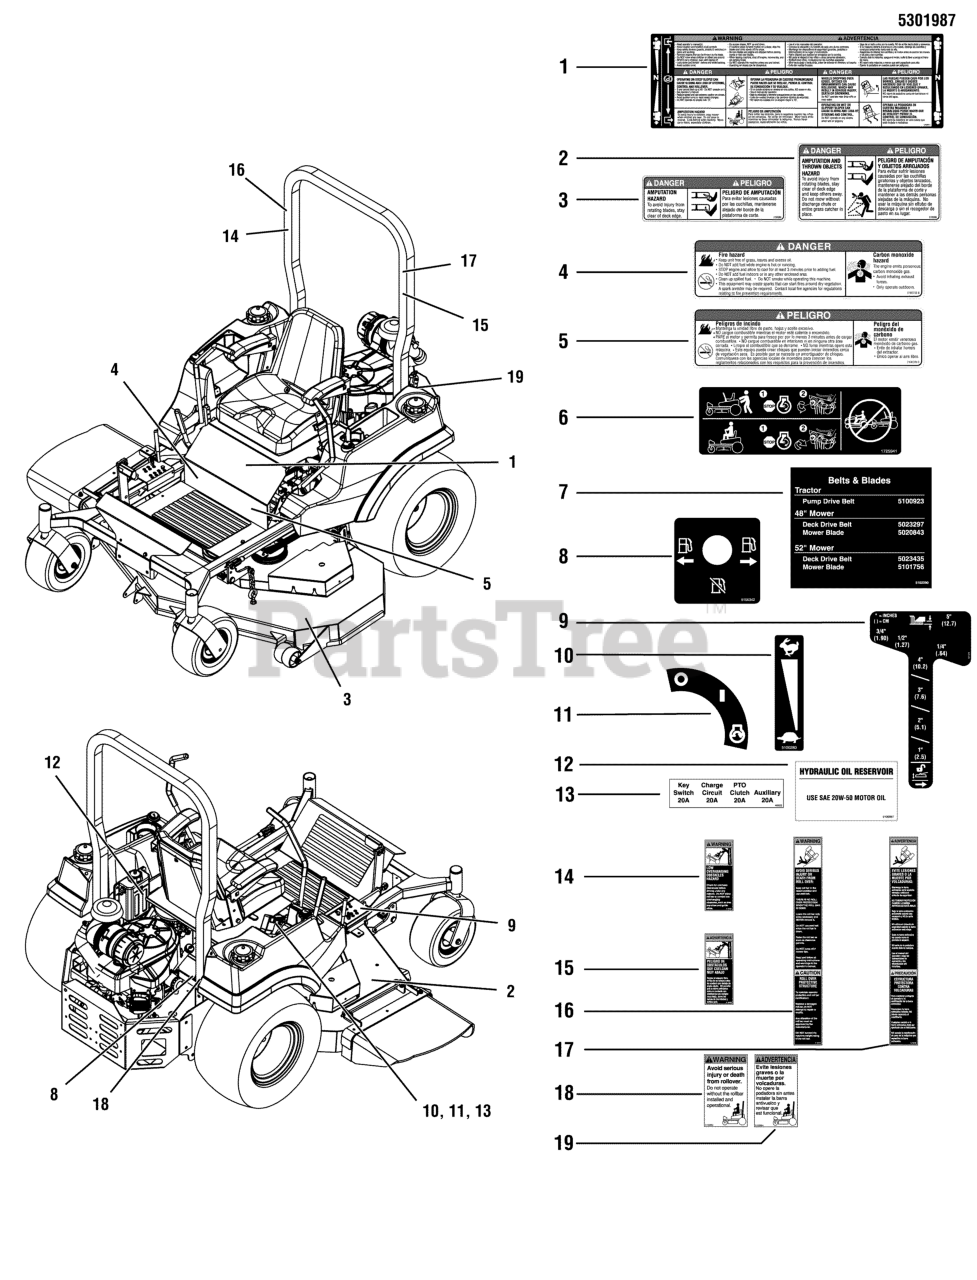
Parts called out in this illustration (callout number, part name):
1	DECAL, MAIN SAFETY
2	DECAL, DANGER, MOWER DISCHARGE
3	DECAL, DANGER, MOWER
4	DECAL, DANGER, FIRE
5	DECAL, DANGER, FIRE (SP)
6	DECAL, CZT HYDRO RELEASE
7	DECAL, BELT & BLADE, SNAPPER PRO 48/52
8	DECAL, FUEL VALVE
9	DECAL-HEIGHT CITATION
10	DECAL, THROTTLE CONTROL
11	DECAL, IGNITION SWITCH
12	DECAL, OIL RESEVOIR
13	DECAL, FUSE LOCATION
14	DECAL, WARNING, ROLL BAR (SV)
18	DECAL, WARNING, ROLL BAR
19	DECAL, WARNING, ROLL BAR, SP
